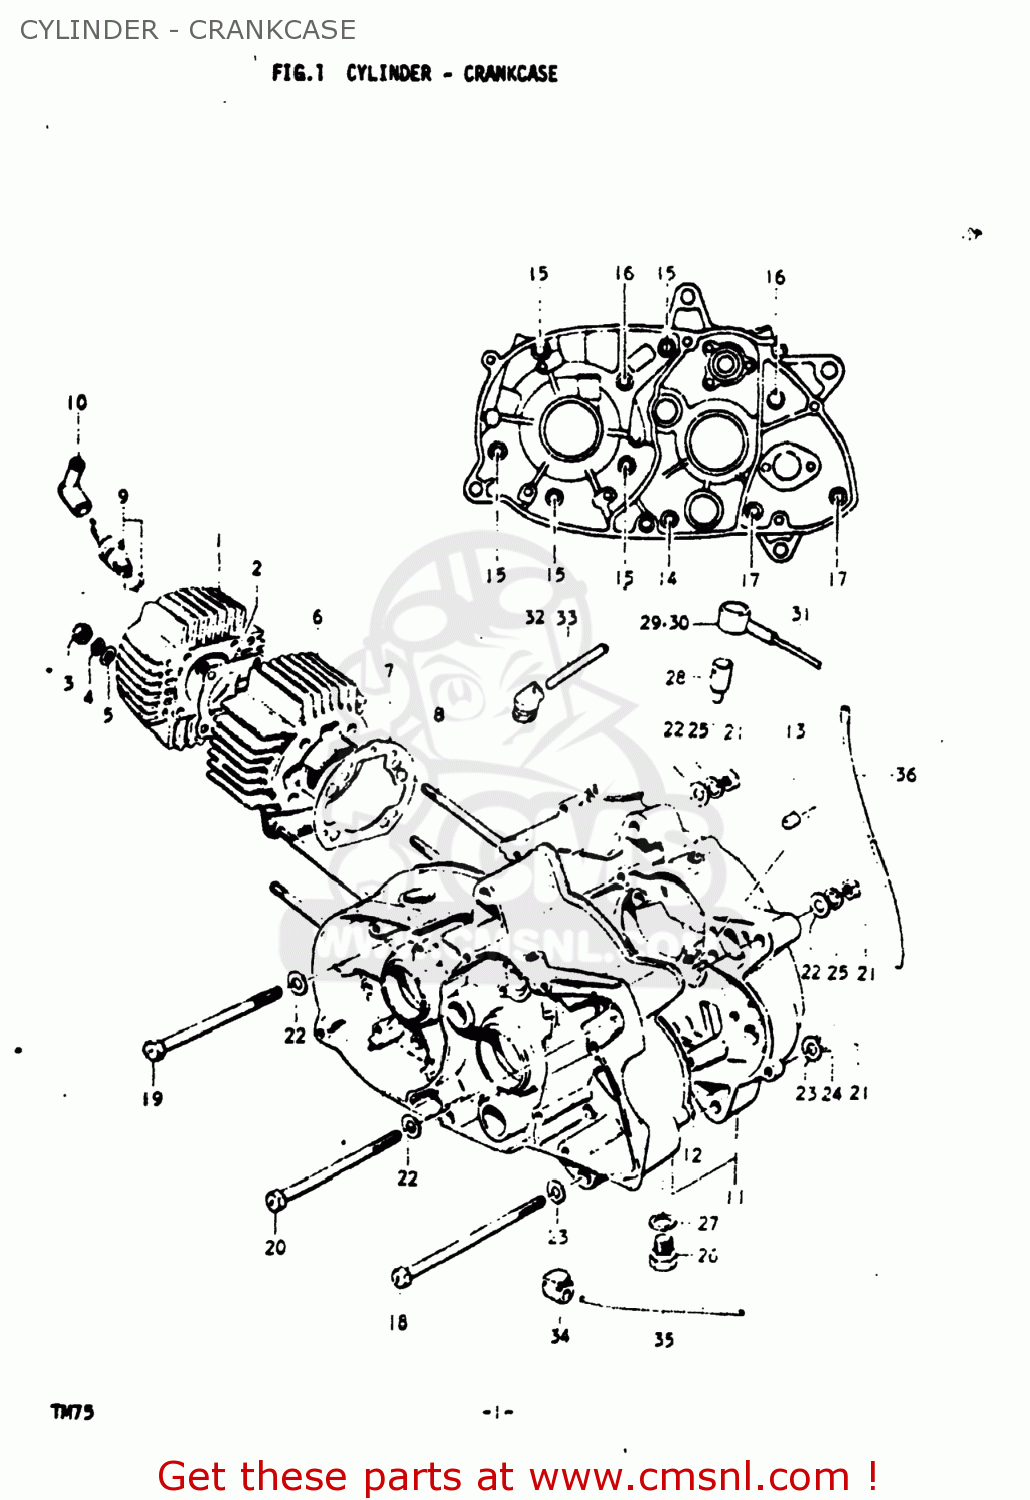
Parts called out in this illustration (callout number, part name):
1	HEAD,CYLINDER
2	GASKET,CYLINDER HEAD (NAS)
3	NUT
4	LOCK WASHER
5	WASHER
6	CYLINDER
7	GASKET,CYLINDER (MCA)
8	BOLT,STUD
9	PLUG,SPARK(B7HS)
10	CAP,SPARK PLUG
11	CRANKCASE SET
12	GASKET,CRANKCASE (MCA)
13	PIN
14	SCREW
15	SCREW (6X45)
16	SCREW
17	SCREW
18	BOLT 8X110
19	BOLT 8X105
20	BOLT 8X100
21	NUT
22	WASHER
23	WASHER (8.5X24X2.3)
24	WASHER,LOCK,8.
25	LOCK WASHER
26	PLUG
27	GASKET(14X19.2X2) (NAS)
28	PLUG,TRANSMISSION BREATHER
29	PLUG,BREATHER
30	GASKET (NAS)
31	HOSE
32	GROMMET
33	HOSE
34	GROMMET
35	HOSE
36	HOSE
